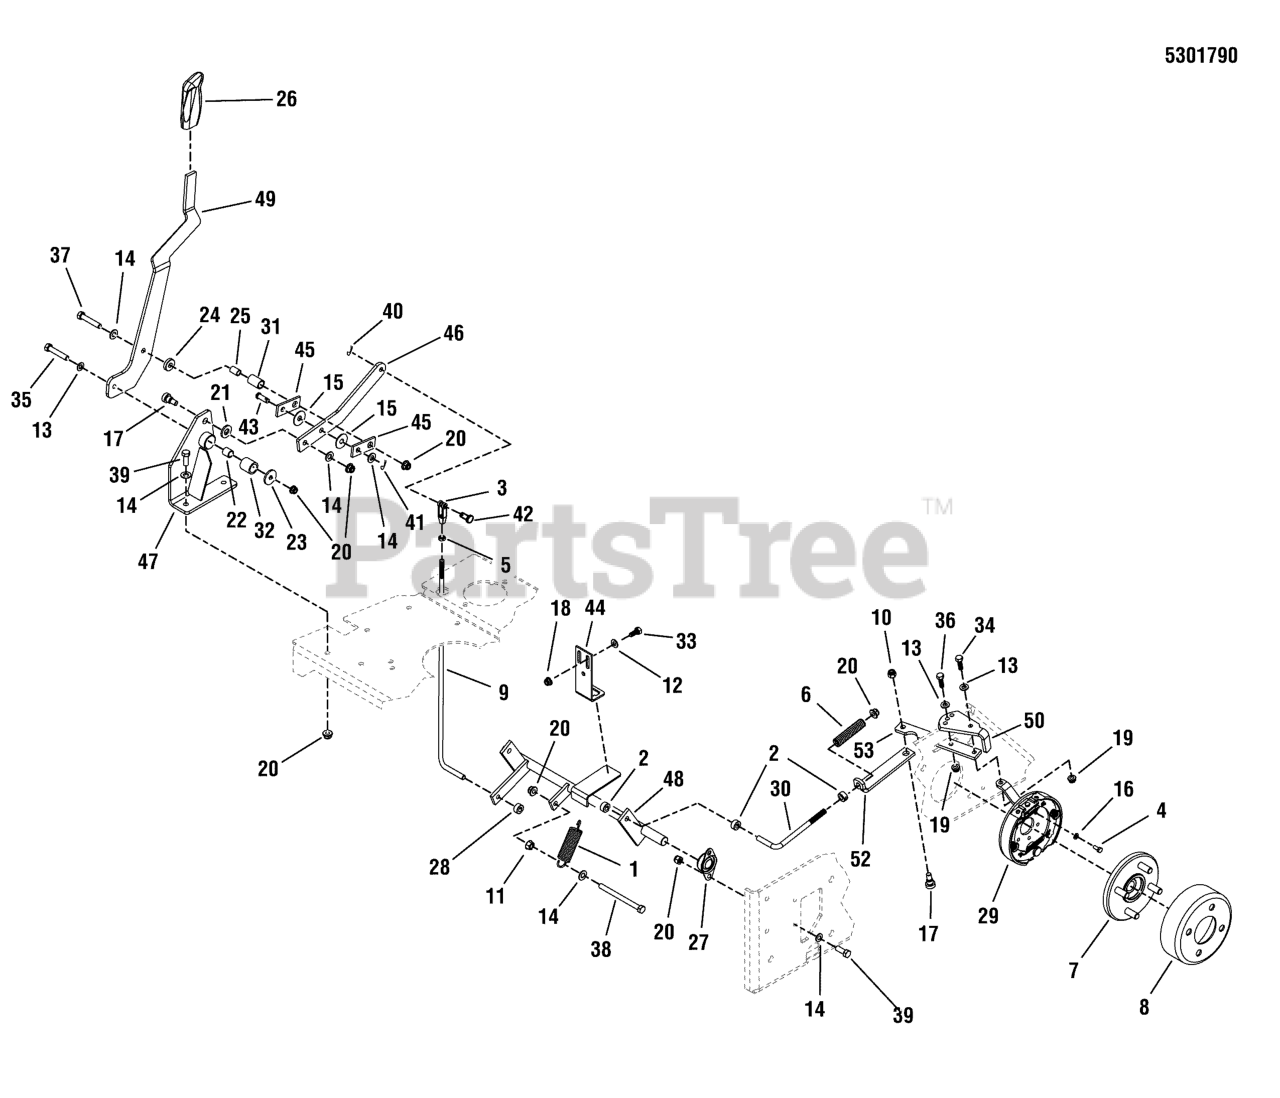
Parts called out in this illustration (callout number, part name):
1	SPRING-EXTN 1.040ODX 04.000LG .105WIRE D
2	COLLAR, 3/8 SET
3	CLEVIS, 5/16-24, PLASTIC
4	CAPSCREW-HEX HEAD M6-1.0X 14MM
5	NUT, 5/16-24 JAM
6	SPRING-COMP, .496ID X 3.00LG X .112WR
7	HUB-W/STUD, 1TPR 800645
8	BRAKE DRUM
9	ROD, BRAKE, 48-52 EVOLUTION
10	NUT, 3/8-16 HEX SIDE LOCK
11	NUT, 3/8-16 HEX SERRATED FLANGE
12	WASHER, 1/4 SAE
13	WASHER, 5/16" SAE
14	WASHER, 3/8 SAE
15	WASHER-3/8 FENDER
16	WASHER, 1/4 LOCK
17	BOLT, 3/8-16 X 3/8, 1/2 SHOULDER
18	NUT, 1/4-20 HEX NYLOCK FLANGE
19	NUT, 5/16-18 HEX NYLOCK FLANGE
20	NUT, 3/8-16 HEX NYLOCK FLANGE
21	WASHER, 1/2 GD9 YZ
22	SPACER, .32 X .75 X 1.06
23	WASHER, .34 X 1.25 X 10 GA
24	SPACER, .39 X 1.00 X .25
25	SPACER, .38 X .50 X .75
26	GRIP, BLACK FLEXIBLE
27	BEARING, BRONZE FLANGE, 3/4"
28	COLLAR, 5/16 SET
29	CAM BRAKE SHOE ASSM, KNOTT
30	ROD, BRAKE LINKAGE
31	SPACER, .564 X .904 X .310, YZ
32	BUSHING, BRASS, 3/4 X 1 X 1
33	BOLT, 1/4-20 X 3/4 GD5 YZ
34	BOLT, 5/16-18 X 1-1/4 GD5 YZ
35	BOLT, 5/16-18 X 2, GD5
36	BOLT, 5/16-18 X 1 GD5 YZ
37	BOLT, 3/8-16 X 2, GD5, CZ
38	BOLT, 3/8-16 X 4-1/2" GD5 CZ
39	BOLT, 3/8-16 X 1" GD5 CZ
40	PIN, 3/32 X 0.750, COT, ZINC/CLEAR
41	PIN, COTTER, 1/8 X 3/4
42	PIN-CLEVIS, 5/16 X 1 YZ
43	PIN, CLEVIS, 3/8 X 1
44	PLATE, SWITCH BRACKET - RED
45	PLATE, BRAKE HANDLE TAB - RED
46	PLATE, BRAKE HANDLE BRACKET - RED
47	WELD, BRAKE HANDLE MOUNT - RED
48	WELD, BRAKE SHAFT, 48 - RED
49	PLATE, HANDLE, PARKING BRAKE - RED
50	PLATE, LINKAGE ADJUSTABLE, LH - RED
51	PLATE, LINKAGE ADJUSTABLE, RH - RED
52	BAR, BRAKE BRACKET -RED
53	LINKAGE, BRAKE LOWER, 48 - RED
